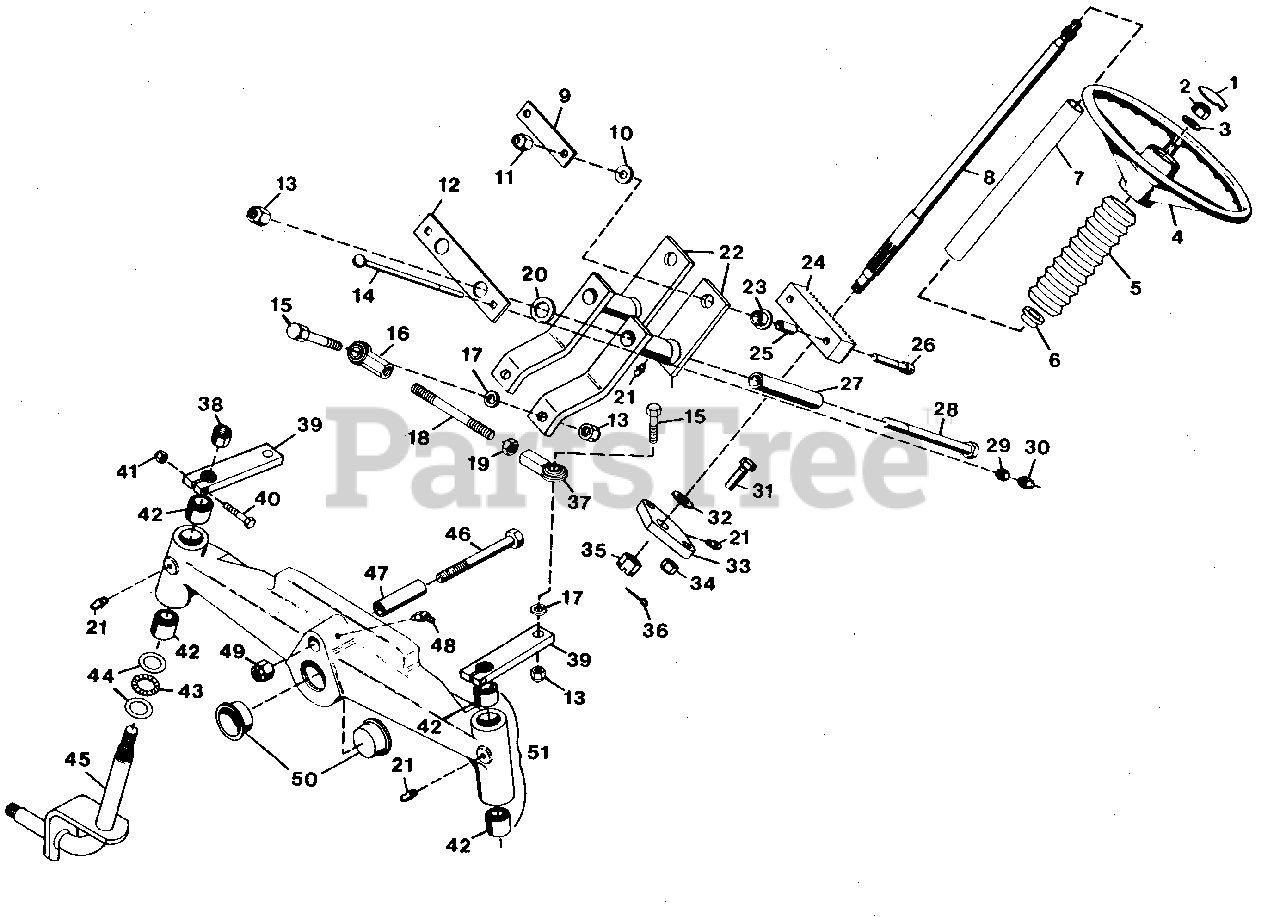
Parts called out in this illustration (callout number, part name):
1	Cap, Steering Wheel
2	Nut, Jam 5/8-11 Hex
3	Washer, Flat .656 x 1.312 x .095
4	Wheel, Steering 8122
5	Bellows, Steering Wheel
6	Bushing, Nylon .760 x 1.00 x .60 Flg
7	Tube, Plastic 1.0 I.D.
8	Shaft, Steering
9	Strap, Rack and Pinion
10	Washer, Flat .375 x 1.125 x .065
11	Nut, Lock 3/8-16
12	Plate, Adjustment
13	Nut, Lock 1/2-13
14	Bolt, 5/16-18 x 5.5 Rd Hd Sq Nk
15	Bolt, Hex 1/2-13 x 2.00
16	Rod End, Steering, LH
17	Washer, Lock 1/2 Reg.
18	Tie Rod, Steering
19	Nut, Jam 1/2-20
20	Race, Brg Thrust .752 x 1.240 x .095
21	Fitting, Lube 1/4-28
22	Weldment, Steering Arm
23	Bearing, Flange (P/M Bronze)
24	Gear, Rack
25	Bushing, .391 x .622 x .670
26	Screw, Cap 3/8-16 x 2.0 HSHD
27	Sleeve, Pivot
28	Bolt, Hex 1/2-13 6.0
29	Nut, Hex 5/16-18
30	Nut, Lock 5/16-18
31	Bolt, Hex 7/16-14 x 1.5
32	Race, Thrust
33	Support, Steering Shaft
34	Nut, Lock 7/16-14
35	Nut, Hex 1/2-13 Slotted
36	Pin, Cotter .09 x 1.00
37	Rod End, Steering, RH
38	Nut, Hex 5/8-11
39	Arm, Tie Rod Axle
40	Bolt, Hex 5/16-24 x 1.75
41	Nut, Lock 5/16-24
42	Bushing, .877 x 1.004 x 1.0
43	Bearing, Needle Thrust
44	Race, Bearing Thrust
45	Weldment, King Pin
46	Bolt, Hex 3/4-10 x 4.5
47	Tube, Axle Pivot
48	Fitting, Lube 45 Deg.
49	Nut, Lock 3/4-10
50	Cap, Front Axle
51	Axle, Steering
